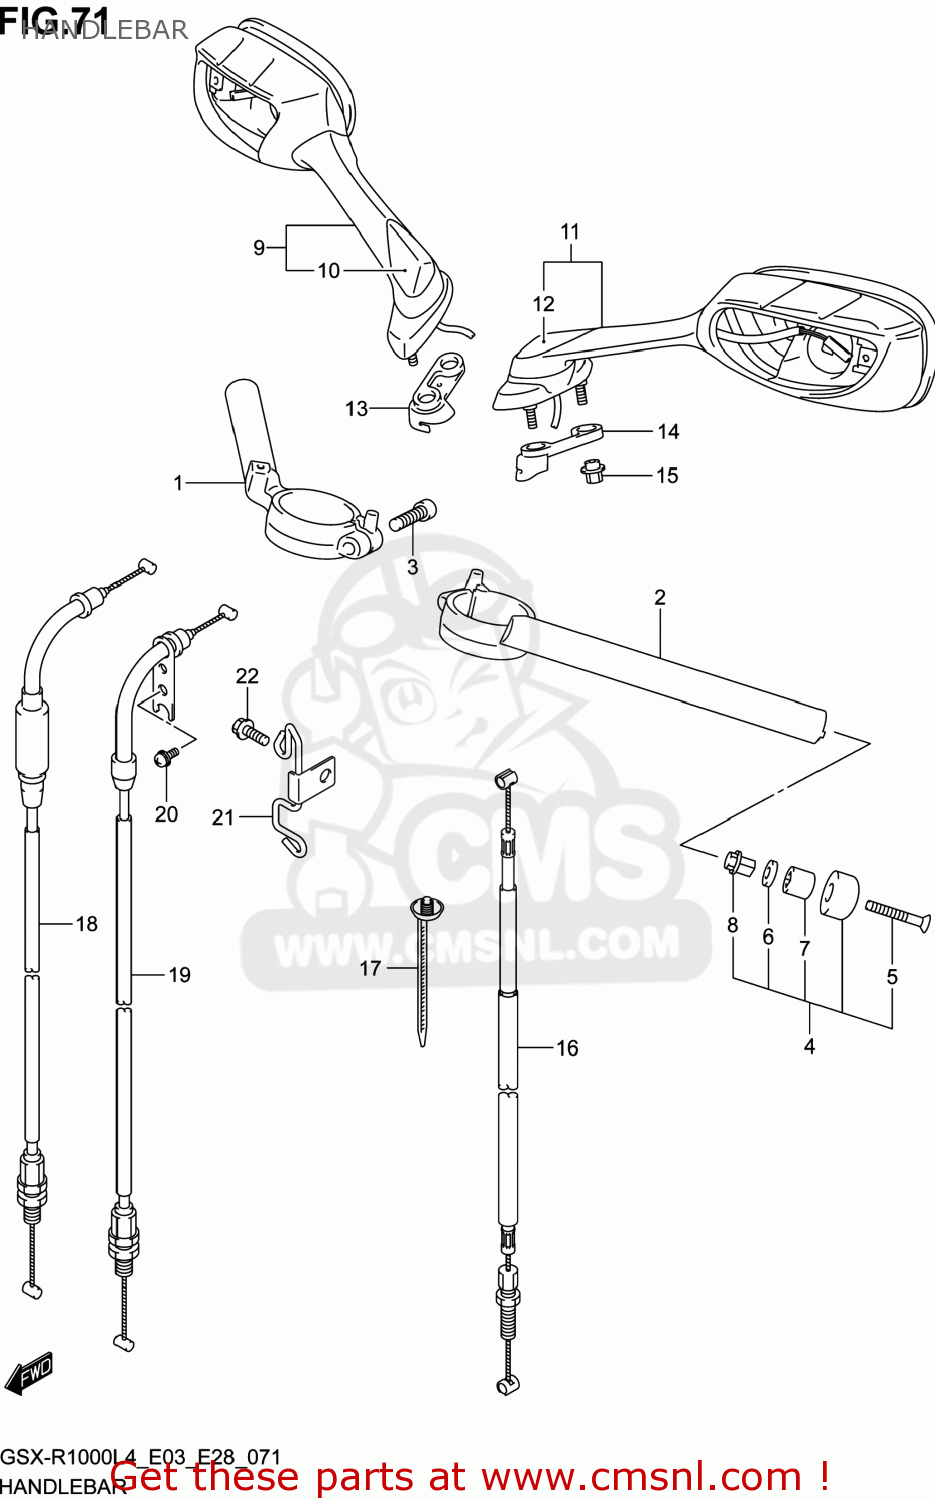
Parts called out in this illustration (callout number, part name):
1	HANDLEBAR,R
2	HANDLEBAR,L
3	BOLT(8X32)
4	BALANCER SET,HANDLEBAR
5	SCREW
6	WASHER(6.5X16X4)
7	EXPANDER,HANDLE BALANCER
8	NUT,HANDLE BALANCER
9	MIRROR ASSY,RR VIEW,R
10	CAP,R
11	MIRROR ASSY,RR VIEW,L
12	CAP,L
13	CUSHION,RR VIEW MIRRROR,R
14	CUSHION,RR VIEW MIRRROR,L
15	NUT,RR VIEW MIRROR
16	CABLE ASSY,CLUTCH
17	CLAMP(L:154)
18	CABLE ASSY,THROTTLE NO.1
19	CABLE ASSY,THROTTLE NO.2
20	SCREW(5X10)
21	GUIDE,CABLE
22	BOLT
